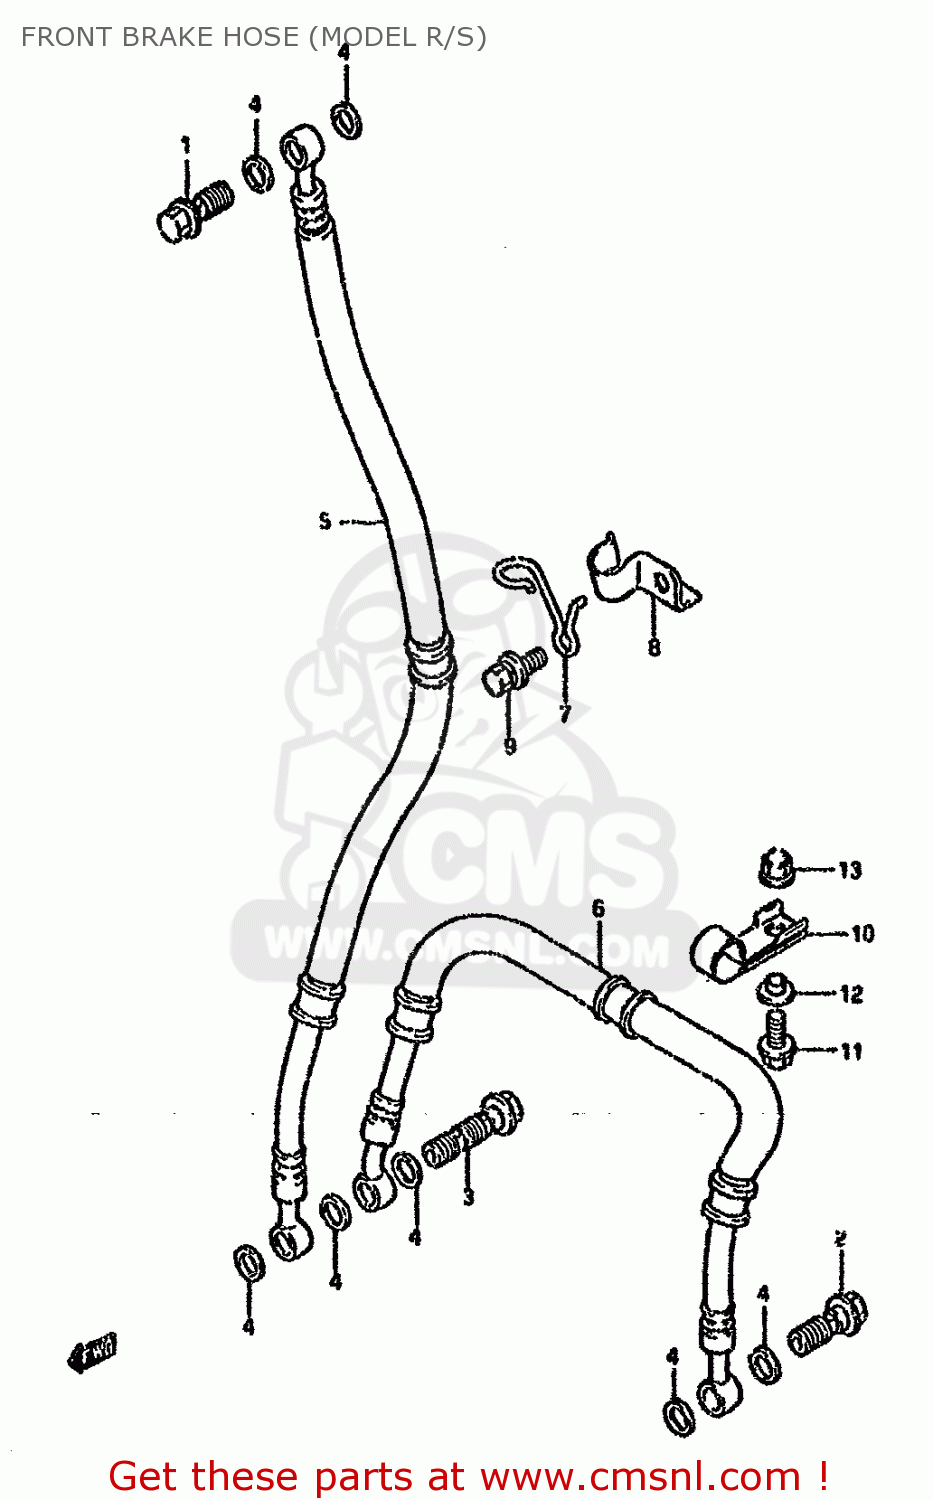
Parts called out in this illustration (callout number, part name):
1	BOLT UNION
2	BOLT UNION
3	BOLT UNION
4	WASHER(10X15X1.5)
5	HOSE,FR BRAKE NO.1
6	HOSE,FR BRAKE NO.2
7	GUIDE,FR BRAKE HOSE
8	CLAMP,FR BRAKE HOSE UPR
9	BOLT
10	CLAMP,FR BRAKE HOSE NO.2
11	BOLT
12	WASHER
13	NUT
